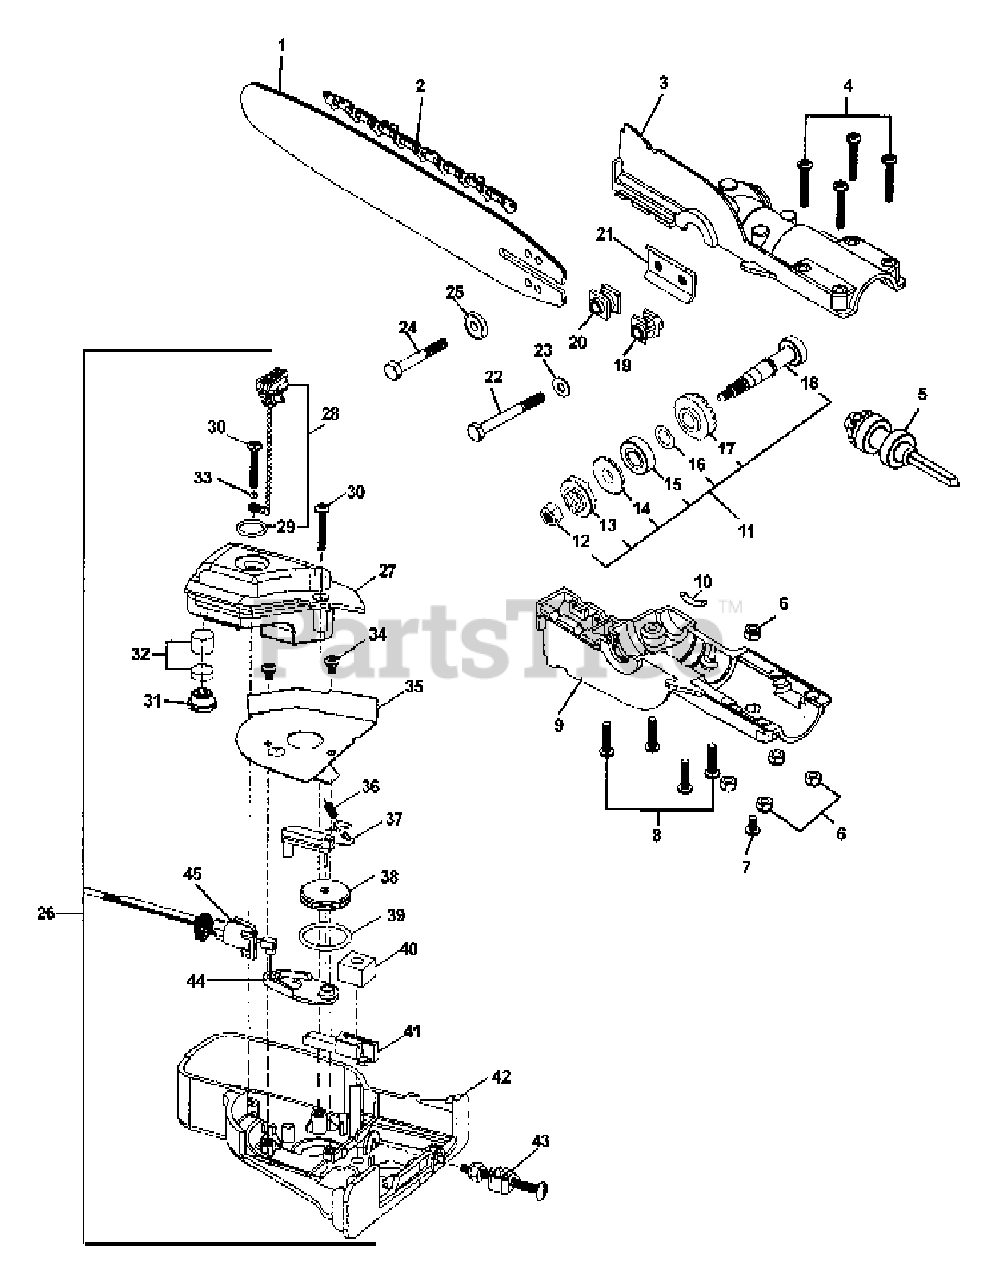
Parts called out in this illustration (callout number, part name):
1	GUIDE BAR - 12"
2	SAWING CHAIN - 90SG - 12" -- MICRO-LITE
3	CASE, GEAR
4	SCREW, TORX 10-24 UNC 1-1/4
5	SHAFT GEAR ASSY
6	NUT, LOCK 10-24 UNC
7	SCREW
8	SCREW, TORX
9	CASE, GEAR - LOWER
11	GEAR SHAFT ASSY
12	NUT, HEX
13	SPROCKET, DRIVE
14	SPACER, SPROCKET
15	BEARING, BALL 6001 DDU
16	WASHER 12
17	GEAR, BEVEL
18	SHAFT, GEAR
20	SPACER
23	WASHER, FLAT
24	SCREW
25	WASHER 6
26	AUTO-OILER ASSY
27	OIL TANK ASSY
28	CAP, OIL
30	SCREW, TORX
31	GROMMET, OIL
32	FILTER, OIL
34	SCREW 8-32×1/4
35	PLATE, PROTECTION
36	SPRING, COMPRESSION
37	LINK, OILER IDLER
38	CAM, OIL PUMP
40	SPACER
42	COVER, OILER
43	TENSIONER ASSY, CHAIN
44	LINK, OILER DRIVE
45	AUTO-OILER ASSY
